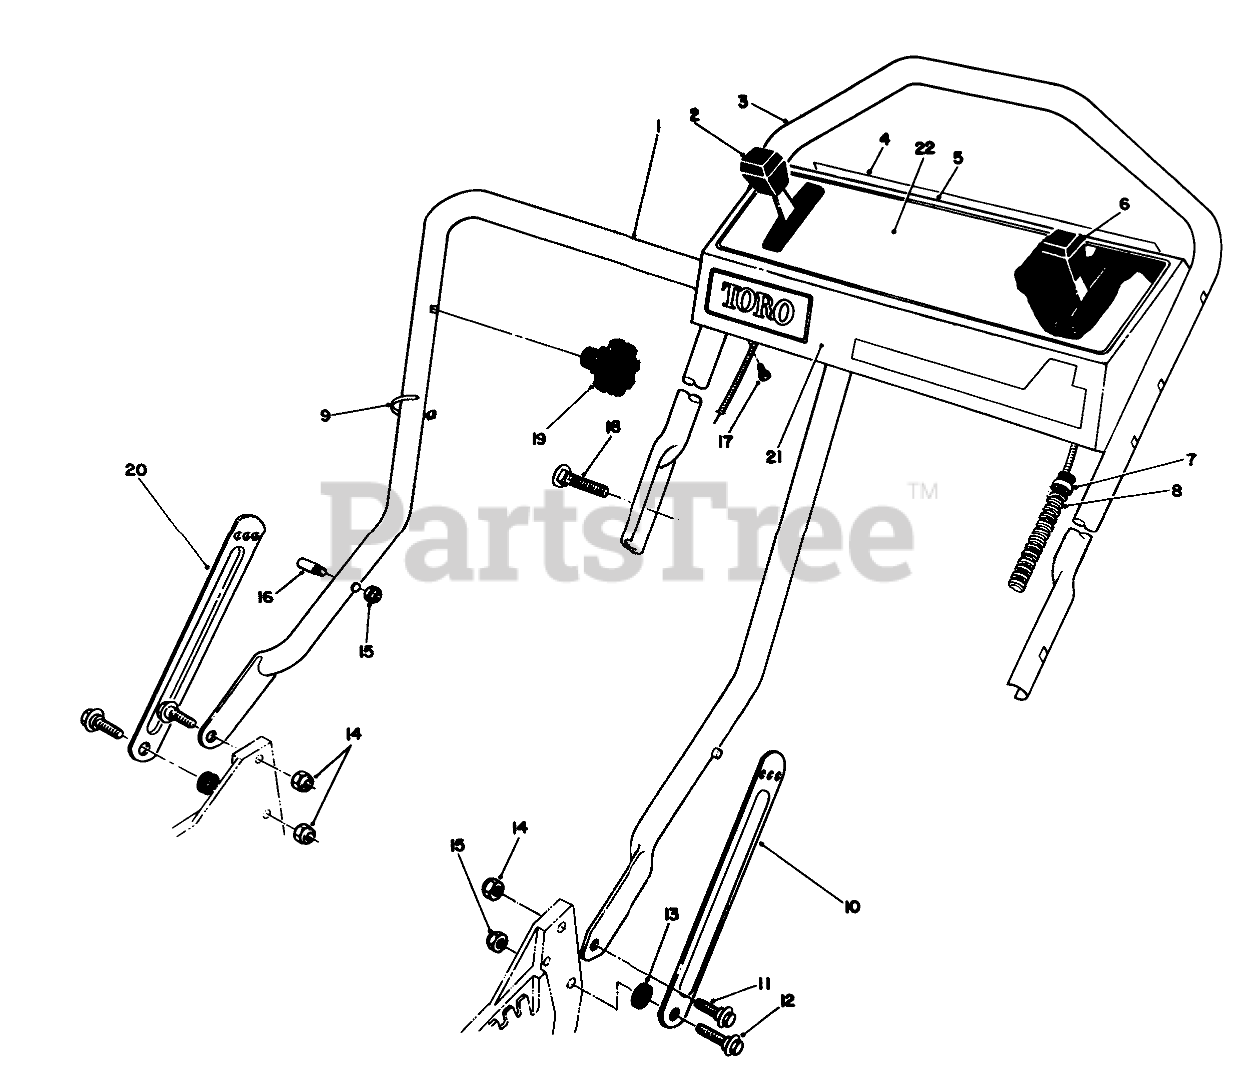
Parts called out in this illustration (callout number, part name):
1	LOWER HANDLE ASM
2	Control-Ground Speed
3	UPPER HANDLE
4	DECAL - PANEL, REAR
5	Panel-Control (Incl. Ref. #4, & 21)
6	THROTTLE CONTROL
7	FITTING-RING
8	CONTROL CABLE COVER
9	TIE-CABLE
10	LH HANDLE LATCH
11	SCREW-SHOULDER
12	SCREW-SHOULDER
13	SPACER
14	NUT-LOCK, NI
15	NUT-LOCK, NI
16	HANDLE PIN
17	SCREW-HWHTF
18	5/16-18 X 2 HNDLE SCREW
20	RH HANDLE LATCH
21	DECAL - TORO
22	DECAL - INSTRUCTION
